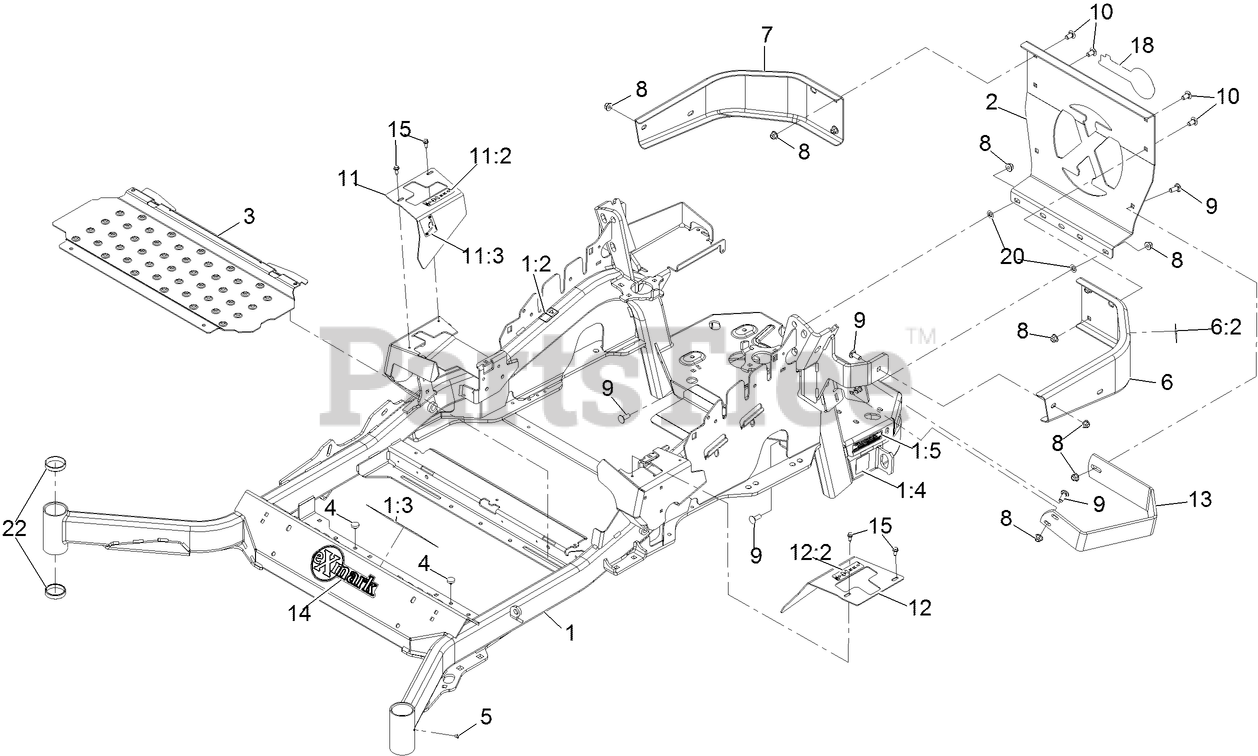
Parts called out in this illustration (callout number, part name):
1	MAINFRAME ASM
1:2	DECAL-WARNING
1:3	DECAL-DANGER
1:4	DECAL-HAZARD, PINCHED FINGER
1:5	DECAL-ARRESTOR, SPARK
2	PLATE,REAR GUARD
6	LH BUMPER ASM
6:2	DECAL-WARNING
7	BUMPER-RH
8	NUT-HF, NI
9	SCREW-CARR
10	SCREW-CARR
11	RH MOTION CONTROL COVER ASM
11:2	DECAL-CONTROL, MOTION
11:3	DECAL-PARK BRAKE, CE
12	LH MOTION CONTROL COVER ASM
12:2	DECAL-CONTROL, MOTION
13	GUARD-MUFFLER
14	DECAL-EXMARK
15	SCREW-HWH
18	DECAL, EXMARK LOGO
20	NUT-PUSH
22	CUP-BEARING
